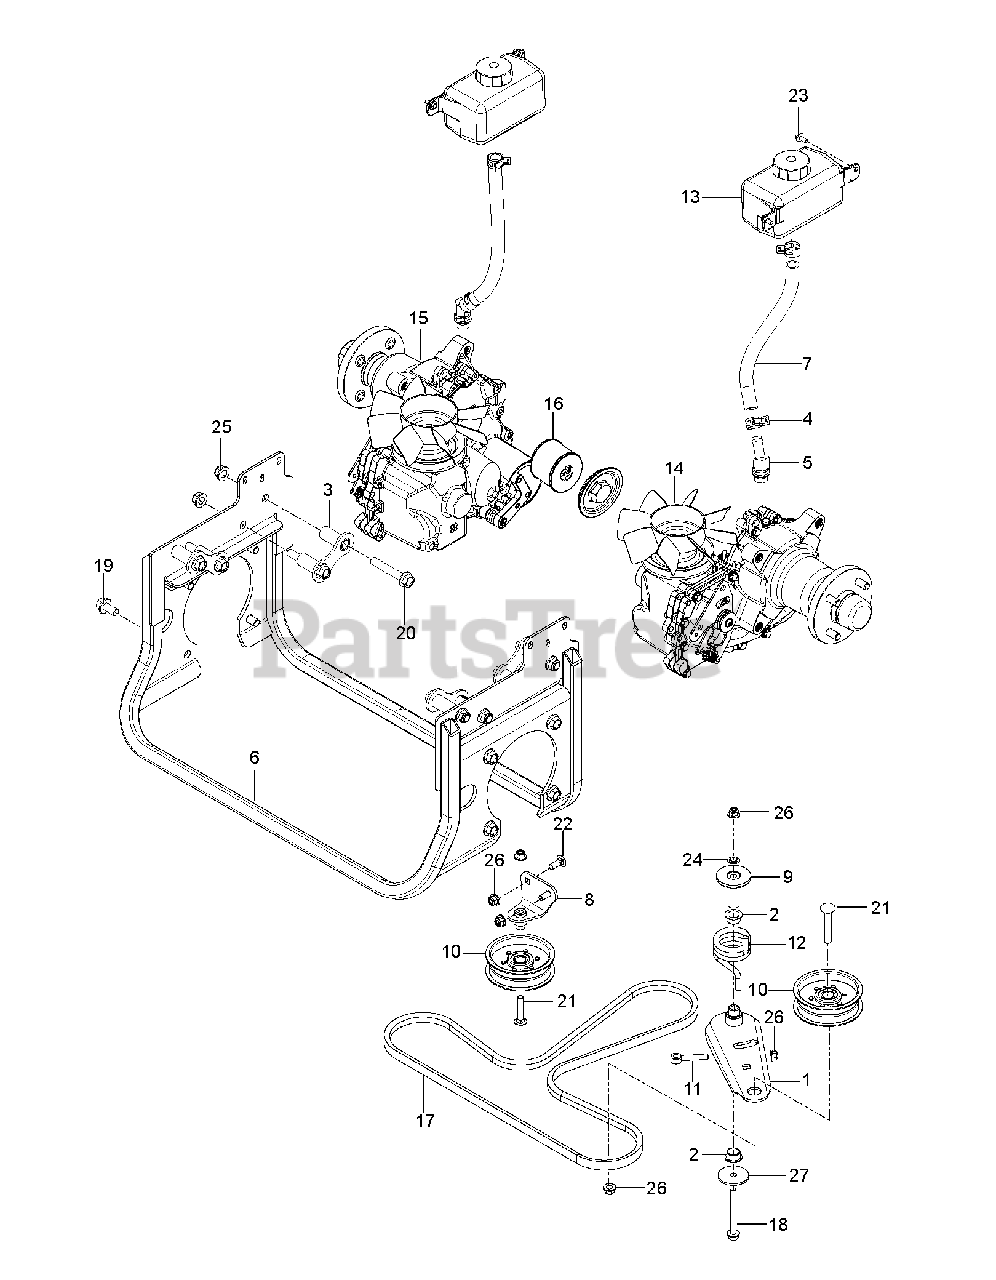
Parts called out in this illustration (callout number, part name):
1	ARM.PNT.IDLER.WELDMENT.EDIP
2	BEARING.FLANGED.PLASTIC.3/4ID
3	BRACKET.PNT.MTG.XMSN.EDIP
4	CLAMP.CT.15/16"HOSE.OD
5	FITTING ELB 45 DEG 10HB-10MAOR
6	FRAME.PNT.XMSN.ZT-4400.EDIP
7	HOSE.HYD.5/8"ID.78"OD.350.PSI
8	MOUNT.PNT.IDLER.FIXED.EDIP
9	SHAFT.MOUNT.ARM.IDLER
10	Backside Idler Pulley
11	ROD.END.3/8-16 X 3.STEEL
12	Torsion Spring
13	HG_TANK, EXPANSION
14	TRANSMISSION.ZT-4400.LH
15	TRANSMISSION.ZT-4400.RH
16	HG_KIT, FILTER W/O-RING ZT5400
17	Belt, BX 77" ZT-4400
18	HHFS 3/8-16 X 3.5 GD 5 ZD
19	HHFS 1/2-13 X 1 GR5 ZD
20	HFFS 1/2-13 X 3 GD 5 ZD
21	RHSNB 3/8C X 2
22	RHSNB 3/8C X 1
23	SCREW.HX.WSH.HD
24	NUT 3/8 PALNUT RTNG BLK PHOS
25	NUT, 1/2-13 HEX FLG NYLOC ZD
26	NUT 3/8-16 HEX FLG NYLOC ZD
27	WASHER 12/32X2X10GA
